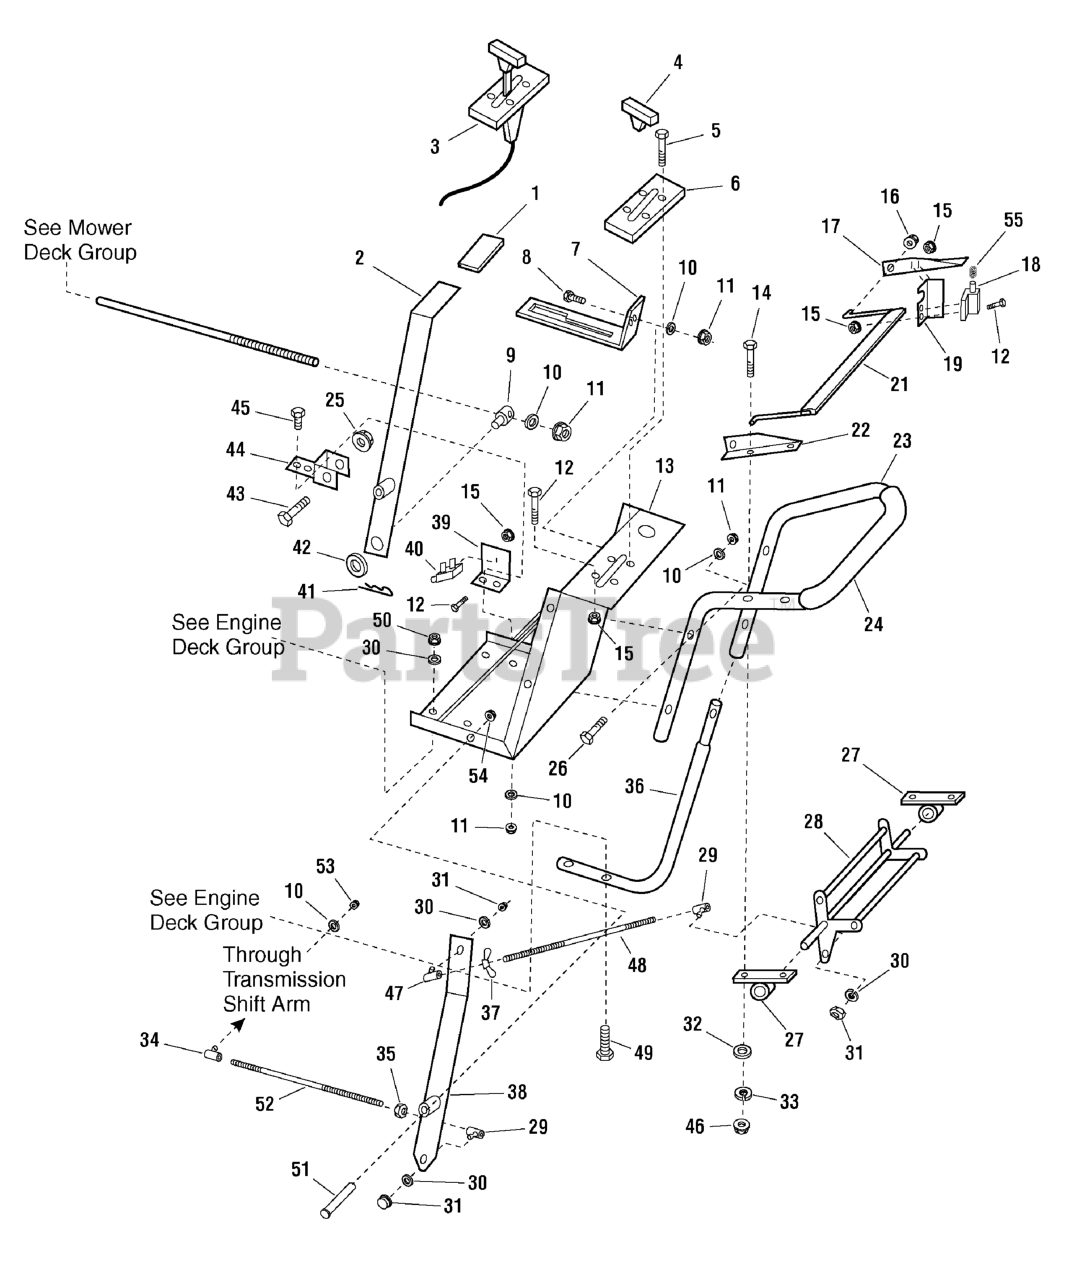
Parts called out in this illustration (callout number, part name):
1	HANDLE GRIP
2	Blade Clutch Engagement Lever
3	Throttle Control Cable Assembly, 13 HP Honda
3	Throttle Control Cable Assembly, 15 HP Kawasaki
3	Throttle Control Cable Assembly, 9 HP Briggs
4	Throttle Control, T-Handle
5	Rivet, 3/16
6	Throttle Speed Indicator Plate
7	Blade Engage Lever Lock Bracket
8	BOLT, 5/16-18 x 3/4
9	Rod, Fitting End
10	Lockwasher, 5/16
11	NUT, Hex, 5/16-18
12	Screw, 8-32 x 3/4
13	Control Deck & Dash Panel
14	BOLT, 1/4-20 x 1-3/4
15	NUT Assembly, 8-32
16	Push Nut, 5/16
17	Safety Bar Pivot Bracket, Left
18	Safety Switch
19	Safety Switch Mounting Bracket
21	Safety Bar
22	Safety Bar Pivot Bracket, Right
23	Upper Handle
24	Foam Handle Cover
25	NUT, Hex Flangelock, 1/2-13
26	BOLT, 5/16-18 x 1-1/2
27	Bearing, 3/4 ID
28	Drive Engagement Bar
29	Ball Joint, 3/8-24, LH
30	Lockwasher, 3/8
31	NUT, Jam, 3/8-24
32	Flatwasher, 1/4
33	Lockwasher, 1/4
34	Ball Joint, 5/16-24
35	NUT, Hex Jam, 3/8-24, LH
36	Lower Handle
37	NUT, Wing, 3/8-24
38	Transmission Drive Intermediate Lever
39	Deck Safety Switch Bracket
40	Deck Safety Switch
41	Bridge Pin, #2
42	Flatwasher, 3/8
43	BOLT, 1/2 x 2-1/2
44	Blade Clutch Engagement Lever Bracket
45	BOLT, 5/16-18 x 1
46	NUT, Hex, 1/4-20
47	Ball Joint, 3/8-24 RH
48	Transmission Engagement Rod, Upper
49	BOLT, 5/16-18 x 1-3/4
50	NUT, Hex, 3/8-16
51	Bolt, Shoulder, 1/2 x 1 -3/8 to 3/8-16
52	Transmission Engagement Rod, Lower
53	NUT, Hex Jam, 5/16-24
54	NUT, Hex Centerlock, 3/8-16
55	Safety switch return spring
